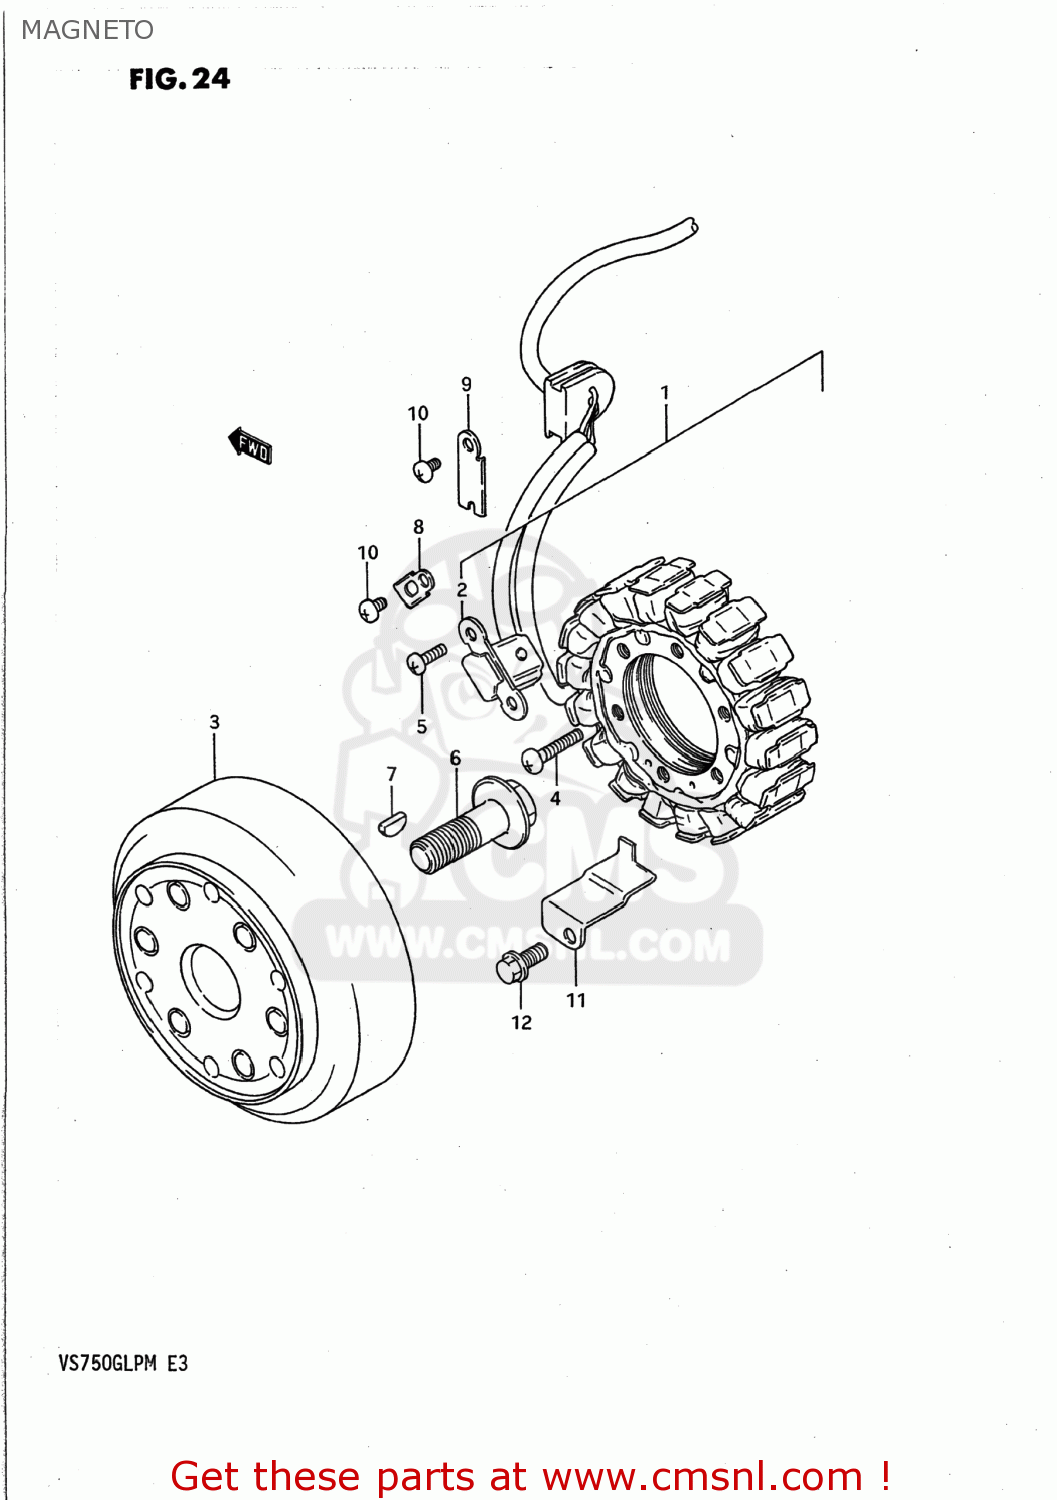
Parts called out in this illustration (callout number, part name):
1	STARTER ASSY
2	SENSOR & WIRE ASSY
3	ROTOR
4	BOLT
5	SCREW
6	BOLT(14X43)
7	KEY 4MM
8	CLAMP,GENERATOR LEAD WIRE
9	CLAMP NO.1,MAGNETO READ WIRE
10	SCREW
11	CLAMP,MAGNETO LEAD WIRE
12	BOLT
